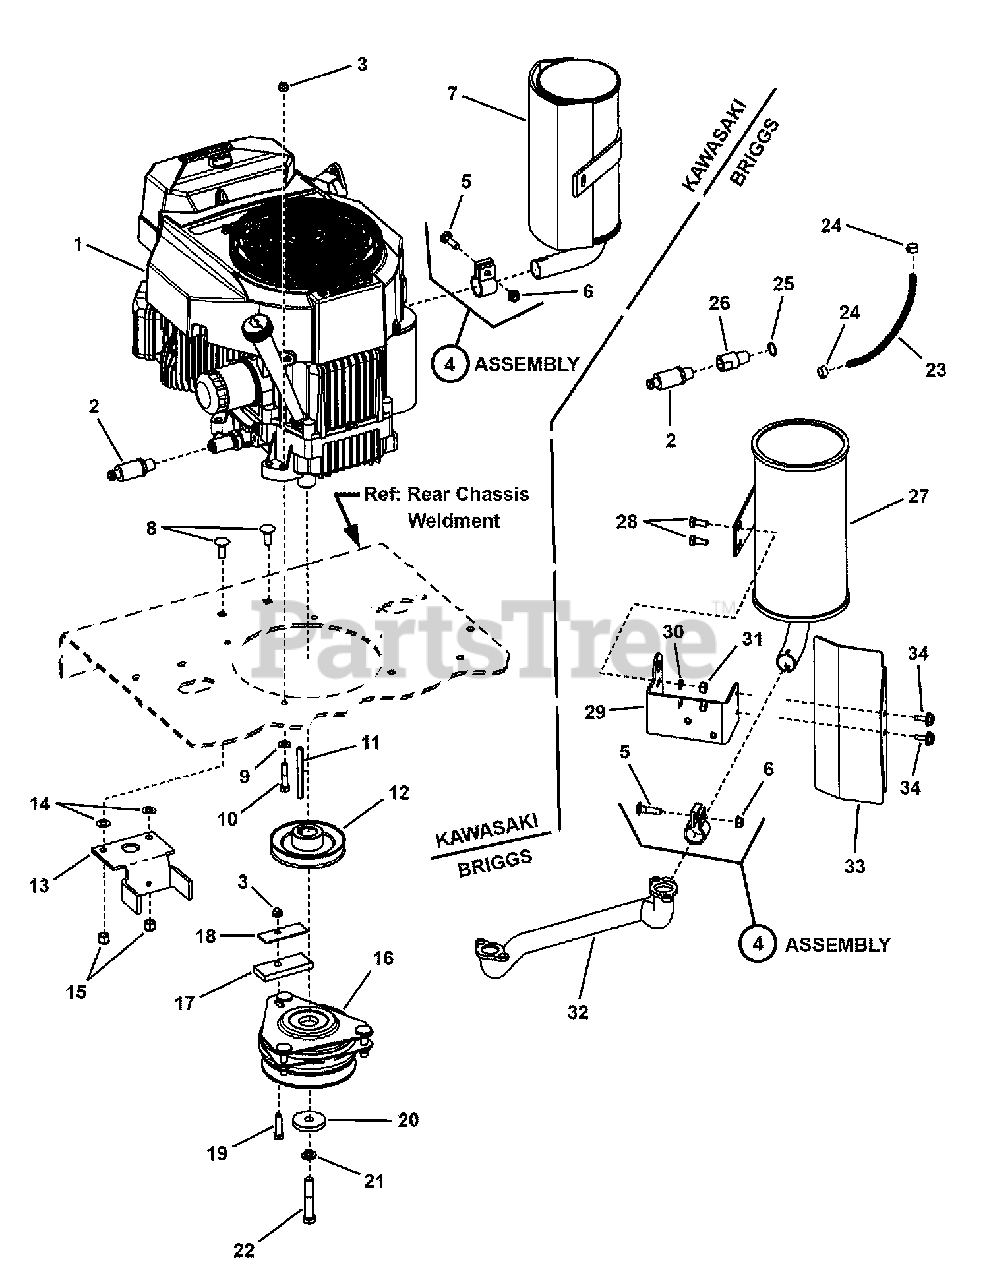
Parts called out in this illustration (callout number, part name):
2	ASSEMBLY, Oil Valve
3	NUT, 5/16-18 Hex Top Lock, GR B
4	CLAMP ASSEMBLY
5	BOLT, 5/16-18 x 1-1/4" Square Neck Carriage, GR 5
6	NUT, 5/16-18 Hex Flange, GR 5
7	MUFFLER
8	BOLT, 3/8-16 x 1" Square Neck Carriage, GR 5
9	WASHER, 5/16" Flat
10	SCREW, 5/16-18 x 1-1/2" Hex Head Cap, GR 5
11	KEY, 1/4" Square x 3-1/4" Long
12	PULLEY, Engine, Hydro Drive
13	BRACKET, Clutch
14	RETAINER, 3/8" Bolt
15	NUT, 3/8-16 HEX NYLON LOCK
16	CLUTCH, Electric (Ogura Model # GT2.5-RM01)
17	BUMPER, Electric Clutch
18	WASHER, Rectangular Steel
19	BOLT, 5/16-18 X 1-1/4 GD5 YZ
20	WASHER, .468 x 1.85 x .25 Flat
21	WASHER, 7/16" Split Lock
22	SCREW, 7/16-20 x 2-1/2" Hex Head Cap, GR 5
23	FUEL HOSE, 1/4" I. D. x 2-1/2"
24	CLAMP, Fuel Line
25	O-RING
26	OIL DRAIN, Short (.375 NPT)
27	MUFFLER
28	SCREW, 5/16-24 x 3/4" Hex Head Cap, GR 5
29	BRACKET, Muffler (Briggs)
30	WASHER, 5/16" Split Lock
31	NUT, 5/16-24 Hex, GR 5
32	EXHAUST MANIFOLD, Vanguard
33	HEAT SHIELD, Briggs
34	SCREW, 1/4-20 x 5/8" Hex Head Self-Tap
